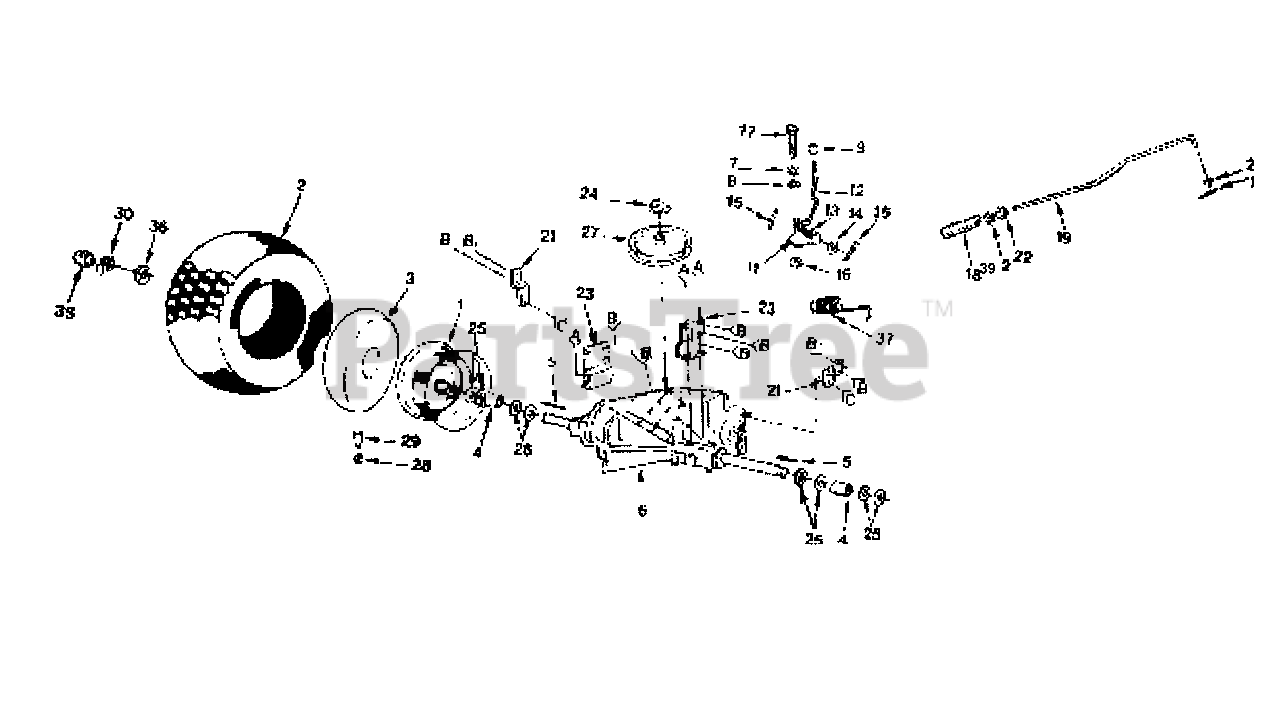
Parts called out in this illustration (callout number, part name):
1	Rim Assembly
2	Tire
3	Tube, Tire
4	Spacer, Split
5	Key, Square 3/16 x 2
6	Transaxle 6 Speed
7	Washer, Lock 1 /4
8	Washer 9/32 x 3/4 x 10 Ga.
9	Knob, Control
10	Cotter Pin 1/8 x 3/4
11	Plate, Rod, Shift
12	Rod, Shifter
13	Spring, Torsion
14	Washer 15/32 x 3/4 x 16 Ga.
15	Pin, Cotter 1/8 x 1
16	Washer, Shift Plate
17	Bolt, Hex 1/4-28 x 3/4 Gr. 8
18	Spring, Rod, Brake
19	Rod, Brake
20	Washer 13/32 x 13/16 x 16 Ga.
21	Strap, Torque
22	Nut, Hex Jam 3/8-16
23	Bracket, Transaxle
24	Ring, Retainer
25	Washer 25/32 x 1-1/4 x 16 Ga.
27	Pulley, Input Transaxle
28	Cap, Valve
29	Stem, Valve
36	Washer 25/32 x 1-5/8 x 16 Ga.
37	Spring, Brake Return
39	Locknut, Hex W/Wsh. 3/8-16 UNC
